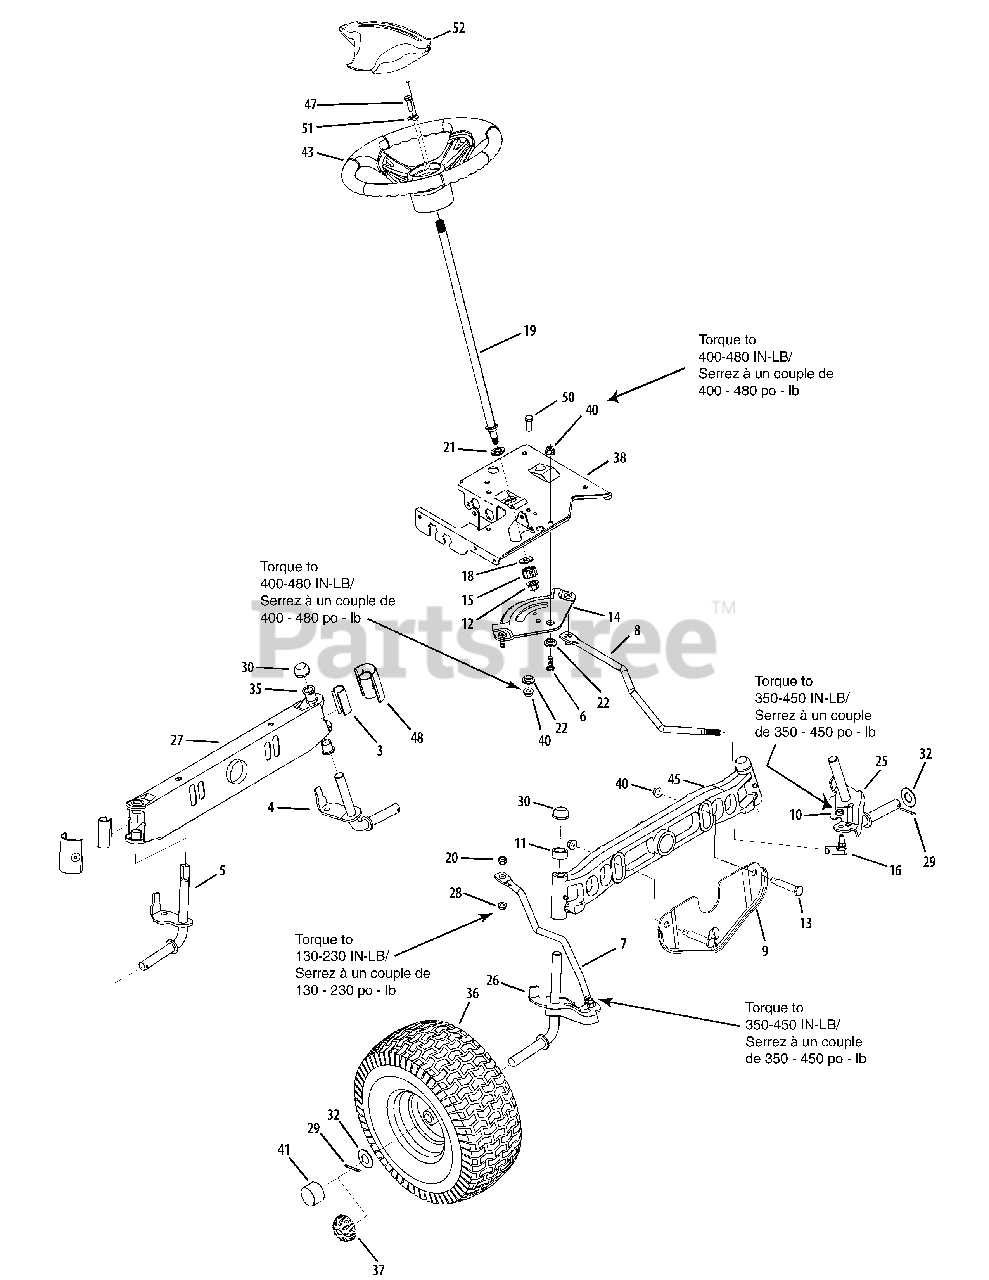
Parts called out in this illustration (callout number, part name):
1	Lower Frame Assembly
3	Axle End Cap - Std.
4	LH Axle Assembly, .750 Dia. (42" Deck)
5	RH Axle Assembly, 750 Dia. (42" Deck)
6	Hex Cap Screw 3/8-16 x 1.00 Gr. 5 Spec.
7	RH Drag Link
9	Front Deck Hanger Brkt. (Style 6)
10	Hex Cent. L-Nut 3/8-24
11	Spacer .71 ID x .125 OD x .56" Lg.
12	Flange Lock Nut, 7/16-20
13	Shoulder Bolt .50 x 2.38: 3/8-16
14	Steering Gear, 11/90 Ra tio
15	Steering Pinion Gear
16	Ball Joint, 7/16 - 20
18	Fl. Washer .510 x 1.120 x .060
19	Steering Shaft, .625 OD x 24.25
20	Plastic Bushing .380 ID
21	Hex Flange Bearing, 5/8
22	Shoulder Spacer
25	LH Axle Assembly, .750 Dia. (46" deck)
25	LH Axle Assembly, .750 Dia. (42" deck)
26	RH Axle Assembly, .750 Dia. (46" deck)
26	RH Axle Assembly, .750 Dia. (42" deck)
28	Hex Flange L-Nut 5/16-18 Gr. 5
29	Cotter Pin 5/32" Dia. x 1.25
30	Push Cap, .750
32	Flat Washer .780 ID X 1.56 OD
32	Flat Washer .781 ID x 1.90 OD
35	Flange Bearing .760 ID x .937 OD
36	Wheel Assembly
37	Hub Cap
38	Steering Support Bracket
40	Hex Flange L-Nut 3/8-16 Gr. F
43	Steering Wheel - 3 Spokes Std. Grip
43	Steering Wheel - 3 Spokes Soft Grip
45	Cast Iron Pivot Bar (.750 dia.)
47	Hex Screw 5/16-18 X 1.00 Spe cial
48	Pivot Bar End Cap
50	Hex Screw 3/16 x 1.00
51	Flat Washer .406 ID x .875 OD x .105
52	Steering Wheel Cover - MTD
